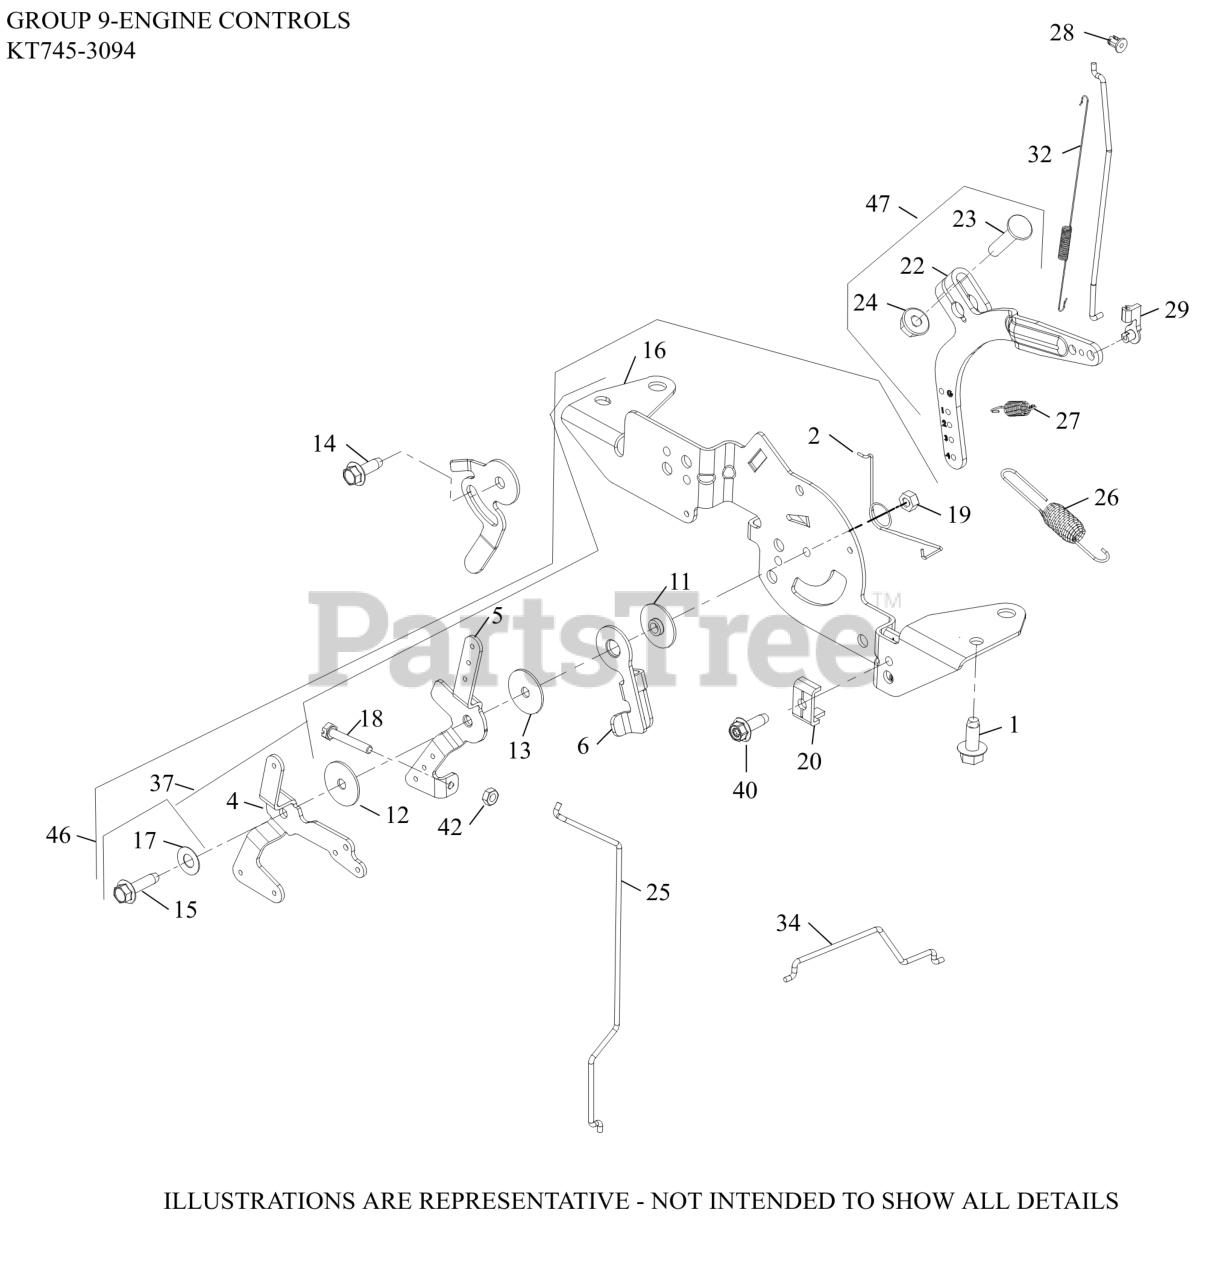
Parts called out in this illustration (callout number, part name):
1	SCREW, THREAD FORMING
2	SPRING, CHOKE RETURN
4	LEVER, CHOKE
5	LEVER, THROTTLE CONTROL
6	LEVER, THROTTLE ACTUATOR
11	SPACER, CONTROL ASSEMBLY
12	WASHER, FLAT 5.5 MM
13	WASHER, FLAT 5 MM
14	SCREW, THREAD FORMING
15	SCREW, THD FRM-USE 25 086 473-S
16	BRACKET, SPEED CONTROL
17	WASHER, SPRING 1/4"
18	SCREW, SLT HD CAP M4X0.7X25
19	NUT, LOCK M5X.8
20	CLAMP, CABLE CABLE
22	LEVER, GOVERNOR - (#2409069S)
23	BOLT, RD HD SQ NECK M6X1.0X25
24	NUT, FLANGE 1/4-20
24	NUT, FLG M6X1.0
25	LINKAGE, CHOKE
26	SPRING, GOVERNOR (PURPLE)
27	SPRING, GOVERNED IDLE
28	BUSHING, LINKAGE RETAINING
29	BUSHING, THROTTLE LINKAGE
32	SPRING, LINKAGE
34	LINKAGE, THROTTLE
40	SCREW, THREAD FORMING
42	NUT, M4X0.7
46	CONTROL ASSEMBLY, DUAL WIRE
47	LEVER, GOVERNOR ASSEMBLY
